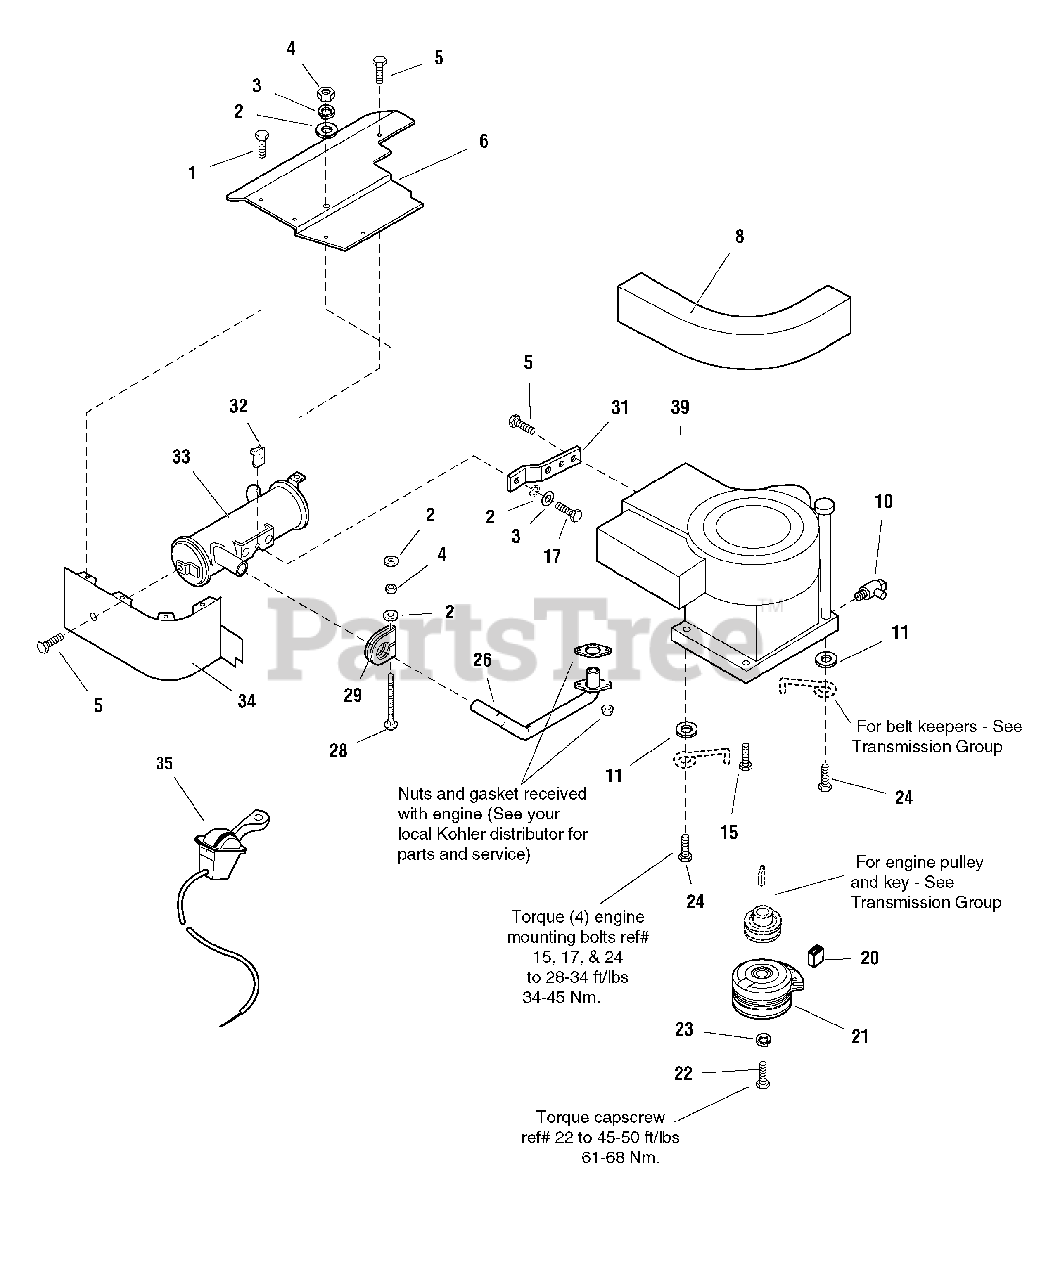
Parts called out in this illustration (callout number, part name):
1	SCREW, Thread Forming, #10-16 x 1/2
2	WASHER, .34
3	LOCKWASHER, 5/16
4	NUT, Hex, 5/16-18
5	CAPSCREW, Hex Head, Taptite, 5/16-18 x 1/2
6	DUCT, R.H., Top
8	SEAL, Air Inlet
10	VALVE, Shut-Off
11	WASHER, Plain
15	CAPSCREW, Taptite, 3/8-16 x 1
17	CAPSCREW, Hex, Whizlock, Flange, 5/16-18 x 1-1/2
20	SLEEVE, Clutch Anchor
21	CLUTCH, Electric, Kit
22	CAPSCREW, Hex Head, 7/16-20 x 2-1/2
23	LOCKWASHER, 7/16
24	CAPSCREW, Taptite, 3/8-16 x 1-1/4
26	PIPE, Exhaust
28	CARRIAGE BOLT, 5/16-18 x 3-1/4
29	CLAMP, Muffler
31	SUPPORT, Muffler
32	SPEED NUT, 5/16-18
33	MUFFLER ASSEMBLY
34	DUCT, Bottom
35	THROTTLE CONTROL, Single
